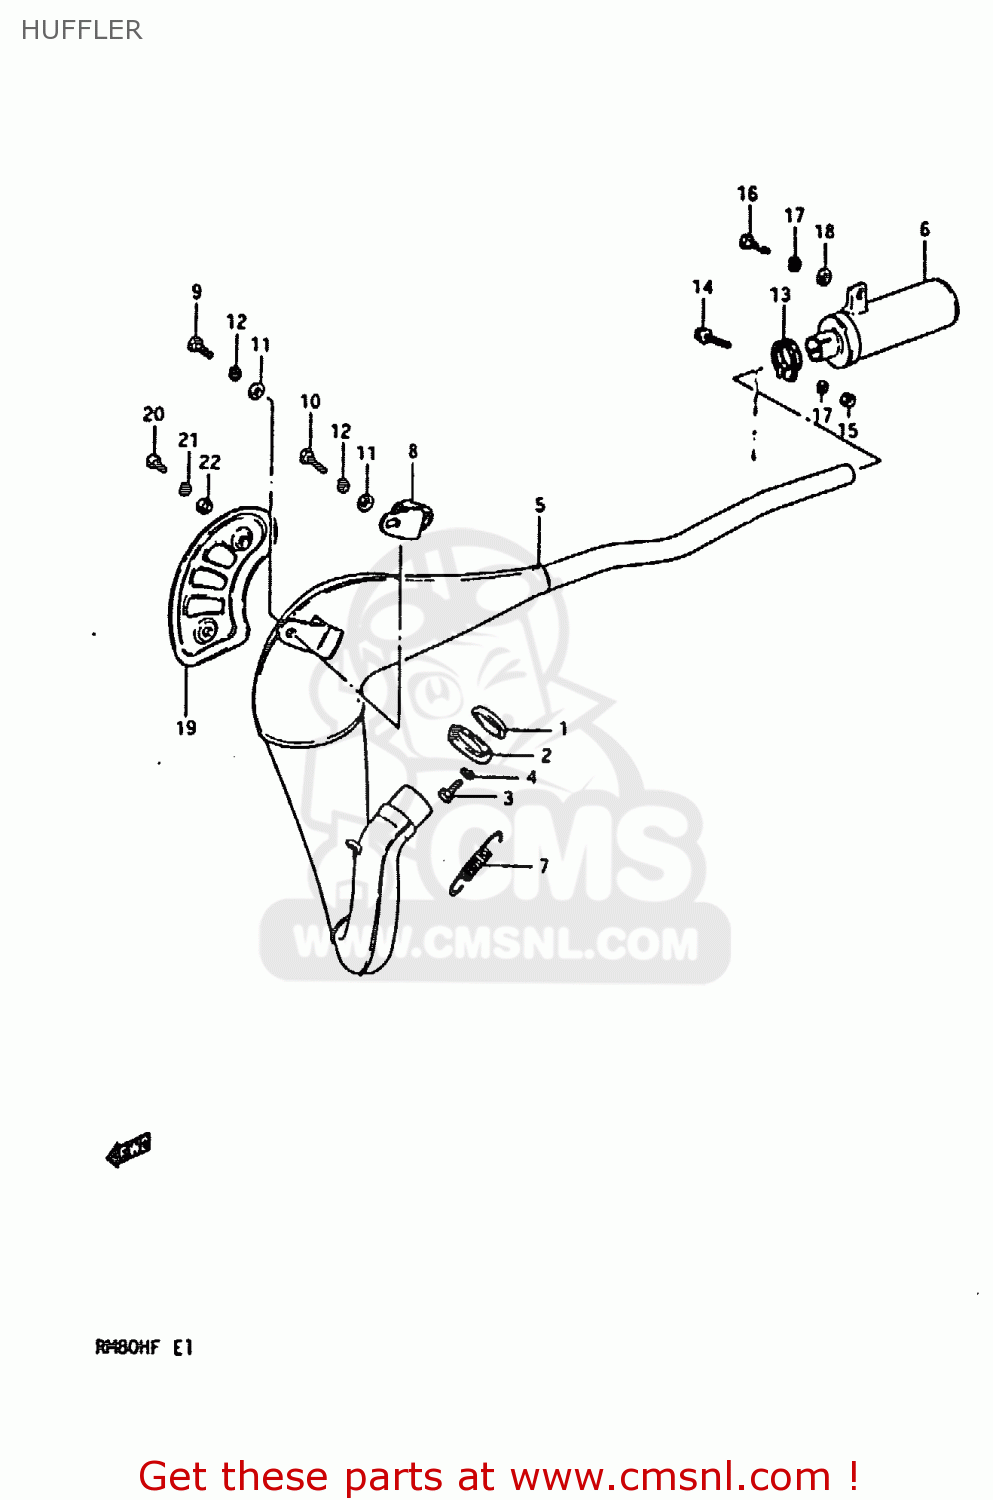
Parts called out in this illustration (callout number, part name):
1	GASKET,EXHAUST PIPE (NAS)
2	CLAMP,EXHAUST PIPE
3	BOLT 6X16
4	WASHER,LOCK
5	MUFFLER, 1ST
6	MUFFLER, 2ND
7	SPRING
8	DAMPER,MUFFLER SUPPORT
9	BOLT
10	BOLT, UPPER
11	WASHER
12	LOCK WASHER
13	CLAMP,MUFFLER SECOND
14	BOLT
15	NUT
16	BOLT
17	LOCK WASHER
18	WASHER
19	COVER,MUFFLER
20	SCREW
21	WASHER,LOCK
22	WASHER
